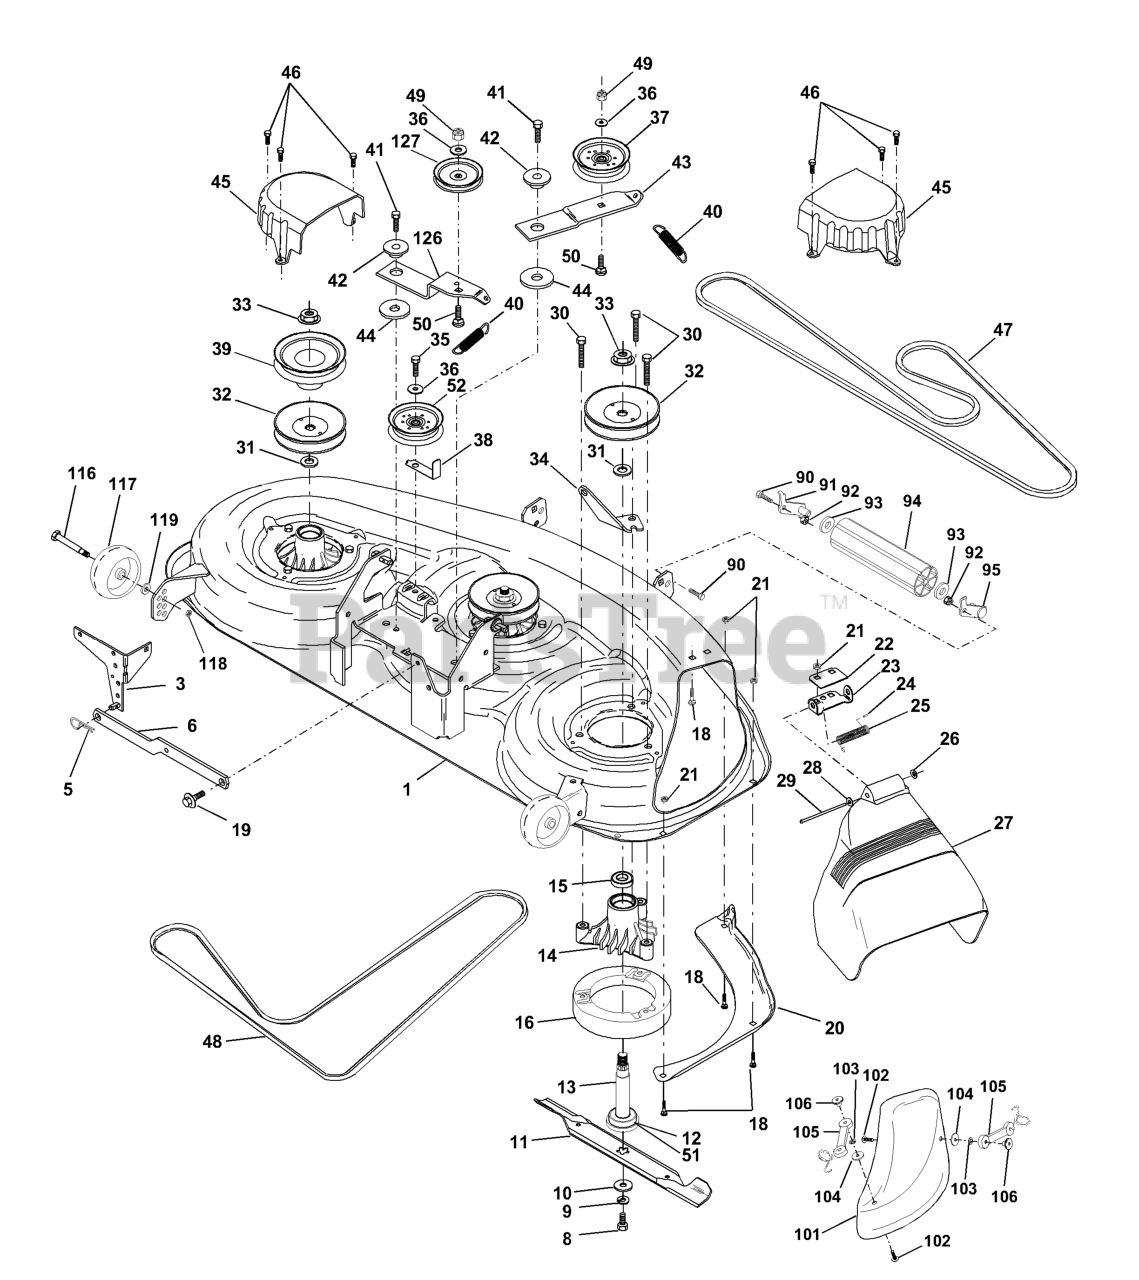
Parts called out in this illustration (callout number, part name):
1	HOUSING MOWER
3	BRACKET SWAY BAR
5	RETAINER-SPRNG RB
6	REAR SUSP ARM
8	BLADE BOLT
9	LOCKWASHER
10	WASHER.BLADE
11	MULCH BLADE 46"
12	BEARING.BALL.#6204.(MANDREL)
13	SHAFT.ASM.W/BEARING
14	HOUSING.MANDREL.44/46" VENT
16	Stripper, Mower Round
18	BOLT
19	BOLT SHD 5/16-18
20	BAFFLE, VORTEX MOWER 46"
21	LOCKNUT
22	STIFFENER BRACKET
23	DEFLECTOR BRACKET
24	CAP-SLEEVE LT
25	SPRING TORSION
26	NUT PUSH M
27	SHIELD, DEFLECTOR MOWER
28	Washer 11/32 x 5/8 x 16 Ga.
29	ROD.HINGE
30	SCREW
31	WASHER
32	PULLEY, MANDREL
33	NUT
34	ANCHOR, SPRING DECK 46"
35	SCREW LT
36	WASHER
37	FLAT IDLER PULLEY
38	KEEPER
39	PULLEY.DRIVEN.DECK.46"
40	SPRING.SEC.44"VEN
41	SCREW
42	SPACER RETAINER
43	ARM IDLER DECK 46"
44	HARDENED WASHER
45	COVER MANDREL 46
46	SCREW.1/4-20X5/8
47	BELT V SECONDARY
48	V-BELT PRIMARY 50"
50	BOLT.3/8-16X1.50
51	WASHER FELT
90	BOLT
91	BRACKET LH (A)
92	NUT
93	Washer 17/32 x 7/8 x 16 Ga.
94	NOSE ROLLER
95	BRACKET RH (B)
101	COVER.MULCH.46"3-BLADE.(2 2)
102	SCREW
103	LOCKWASHER #10
105	LATCH ASSEMBLY
106	WELDNUT
116	BOLT, SHOULDER
117	WHEEL GAGE DONUT
118	LOCKNUT
119	WASHER.5/16.FLAT.STE.STD.
126	ARM IDLER PRIM 46
127	PULLEY.IDLER.4.25
